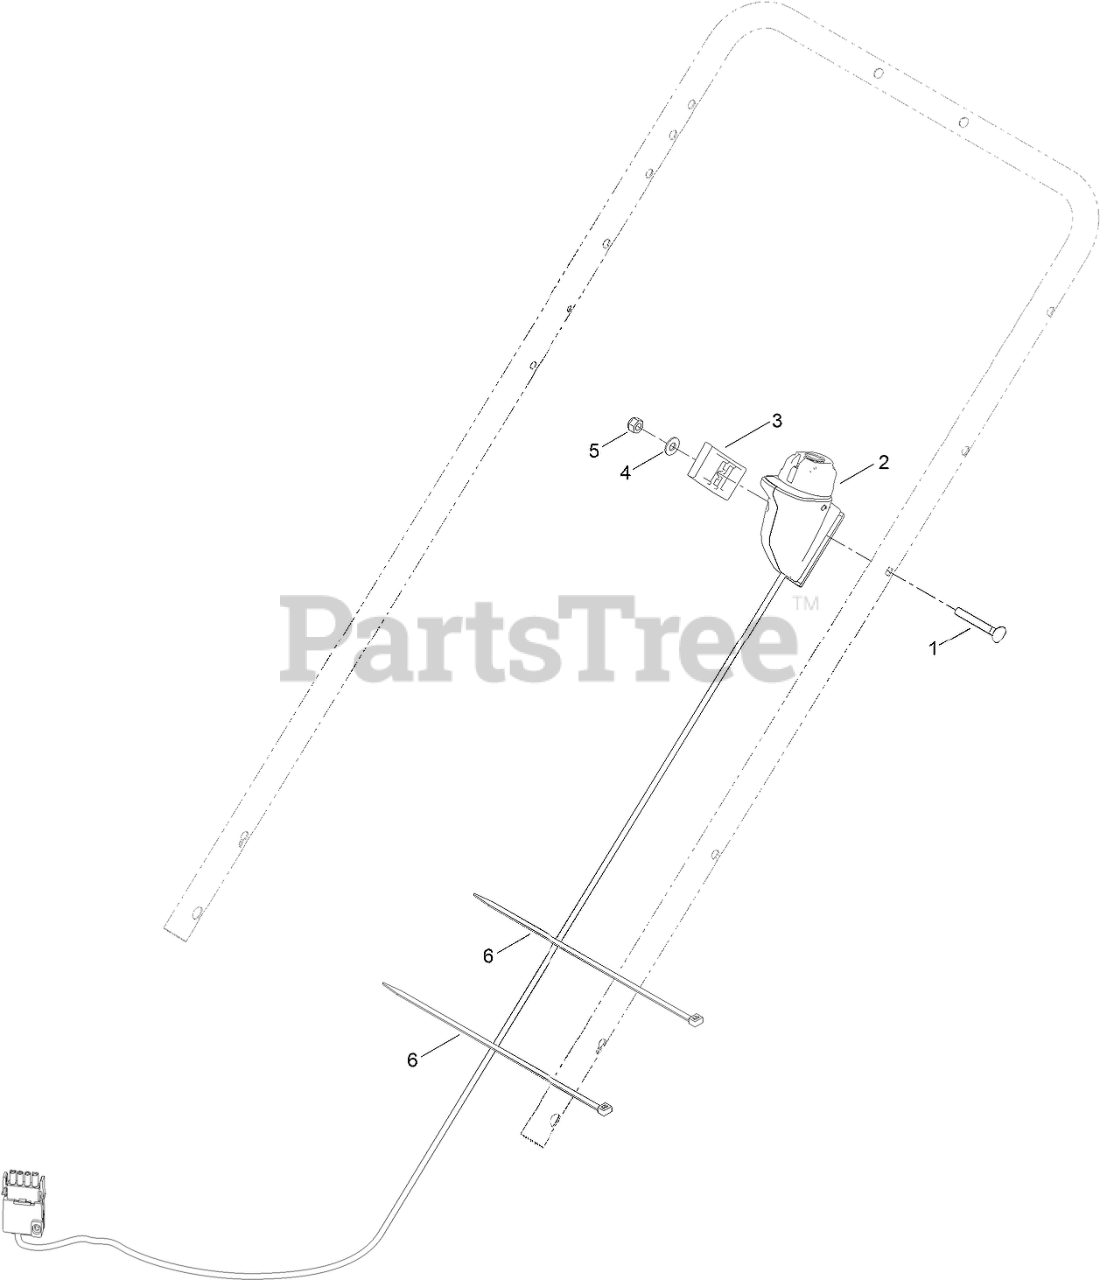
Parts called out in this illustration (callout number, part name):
1	SCREW
2	STARTER SWITCH ASM
3	CLAMP-CABLE
4	WASHER-FLAT
5	NUT-LOCK, NI
6	TIE-CABLE
